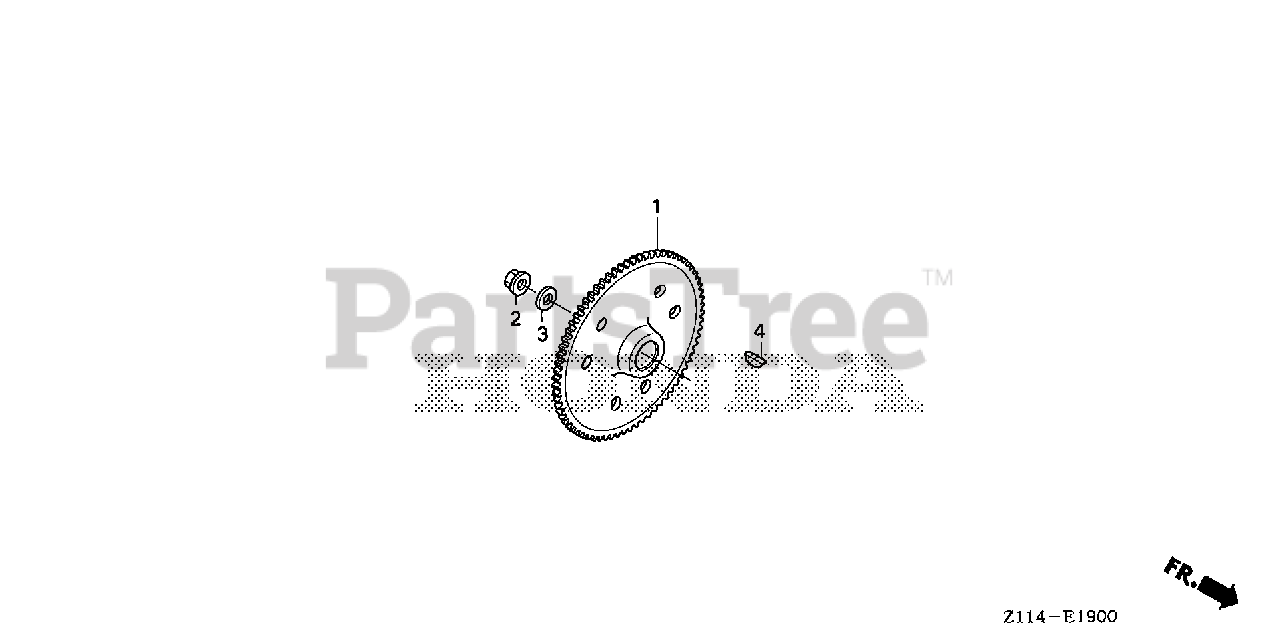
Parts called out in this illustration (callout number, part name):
2	NUT, SPECIAL (16MM)
3	WASHER, FLYWHEEL
4	KEY, SPECIAL WOODRUFF (25X18)
